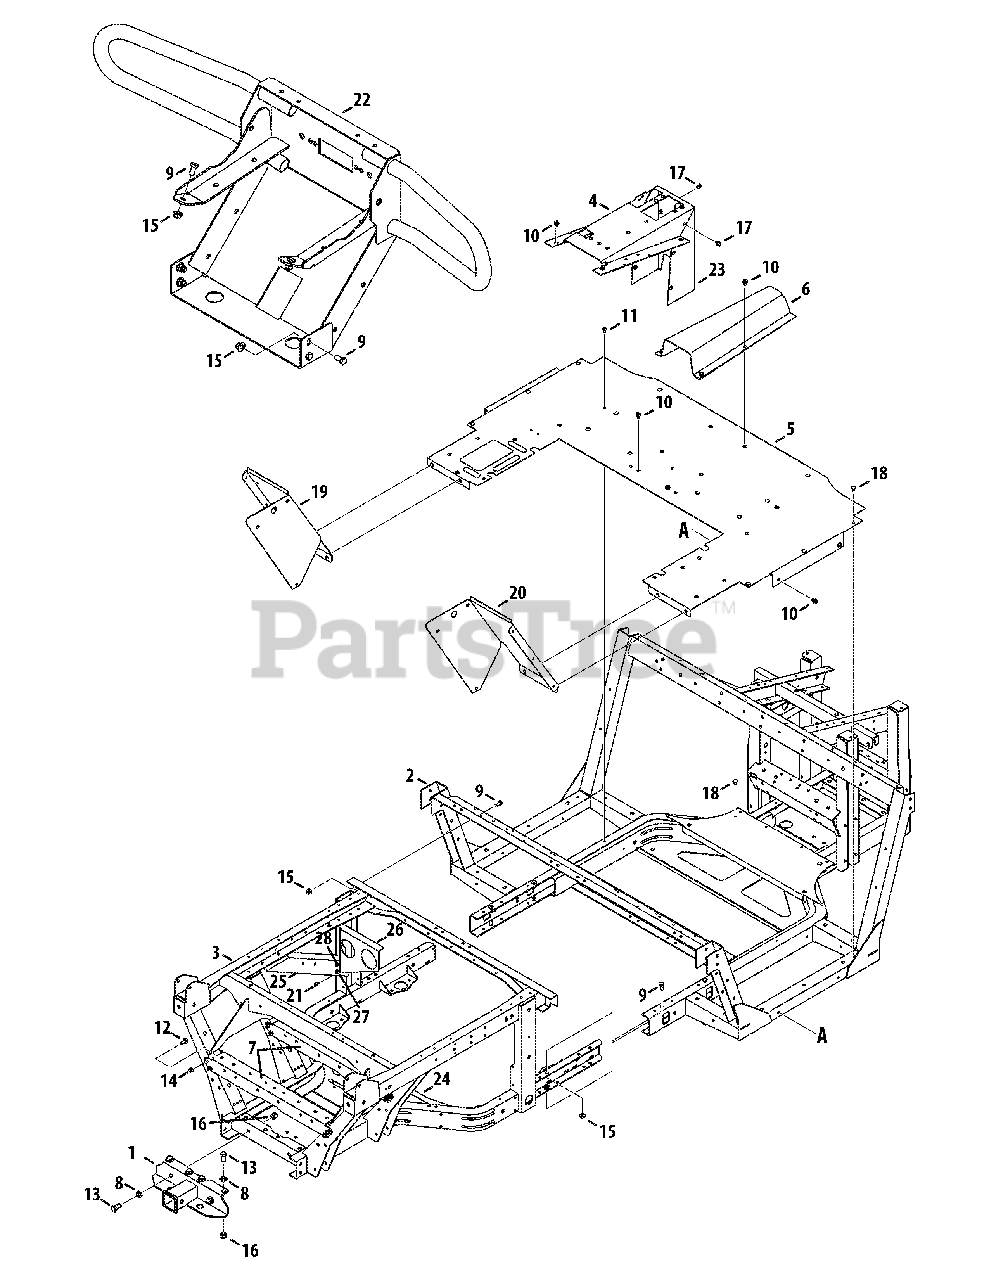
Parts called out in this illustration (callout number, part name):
1	Hitch Assembly, receiver Rr
2	Frame Assembly, front, uv
3	Frame Assembly, rear, uv
4	Plate, console, 4x4, top
6	Cover, front, 4x4
7	Channel, support, rear
8	Washer, Flat, .510 x 1.00 x .060
9	Screw, 3/8-16 x .75, gr5, std
10	Screw, tt, 5/16-18 x 0.500
11	Screw, ab, 1/4-14, 0.625
12	Hex Head Screw, 5/16-18
12	Screw, Hxflg, 5/16-18
13	Screw, 1/2-13, 1.00, gr5, std
14	Nut, Flange Lock, 5/16-18, Nylon
15	Nut, Flange Lock, 3/8-16, Nylon
16	Nut, Hex Lock, 1/2-13, Nylon
17	Screw, tt, 5/16-18 x 0.500
18	Clip, Panel, ret,
19	Bracket, Lh, Shield
20	Bracket, Rh, Shield
21	Screw, tt, 1/4-20 x .500
22	Bumper Assembly, front
23	Plate, console, 4x4, front
24	Bracket Assembly, ISO, Trans/ Eng
25	Bracket Assembly, Air Filter Mnt
26	Bracket Assembly, Supt, Hose
27	Hex Head Screw, 1/4-20 x .620
28	Nut, Flange Lock, 1/4-20
